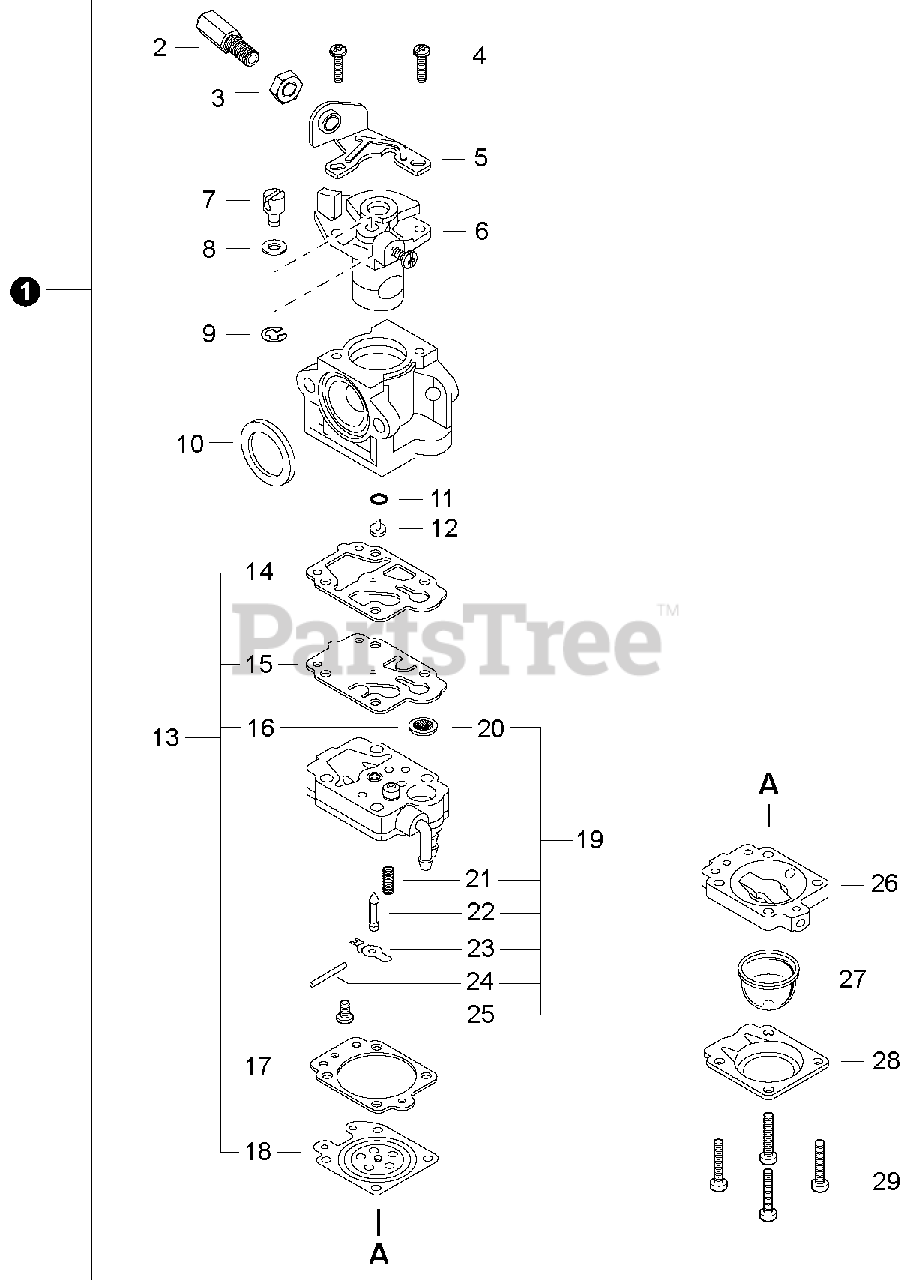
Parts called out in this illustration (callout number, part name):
1	CARBURETOR WYJ-335
2	NUT, CABLE ADJUST
3	NUT - 7
4	SCREW
5	BRACKET, THROTTLE CABLE
6	THROTTLE VALVE ASSY
7	SWIVEL
8	WASHER
9	RING, RETAINING
10	SEAL
11	O-RING
12	JET, MAIN - 37
13	DIAPHRAGM/GASKET KIT
14	GASKET, PUMP
15	DIAPHRAGM, PUMP
16	STRAINER
17	GASKET, METERING
18	DIAPHRAGM, METERING
19	PUMP BODY ASSY
20	STRAINER
21	SPRING, METERING LEVER
22	VALVE, INLET NEEDLE
23	LEVER, METERING
24	PIN, METERING LEVER
25	SCREW, METERING LEVER PIN
26	PURGE BASE ASSY
27	BULB, PURGE
28	RETAINER, PURGE BULB
29	SCREW, PUMP COVER
